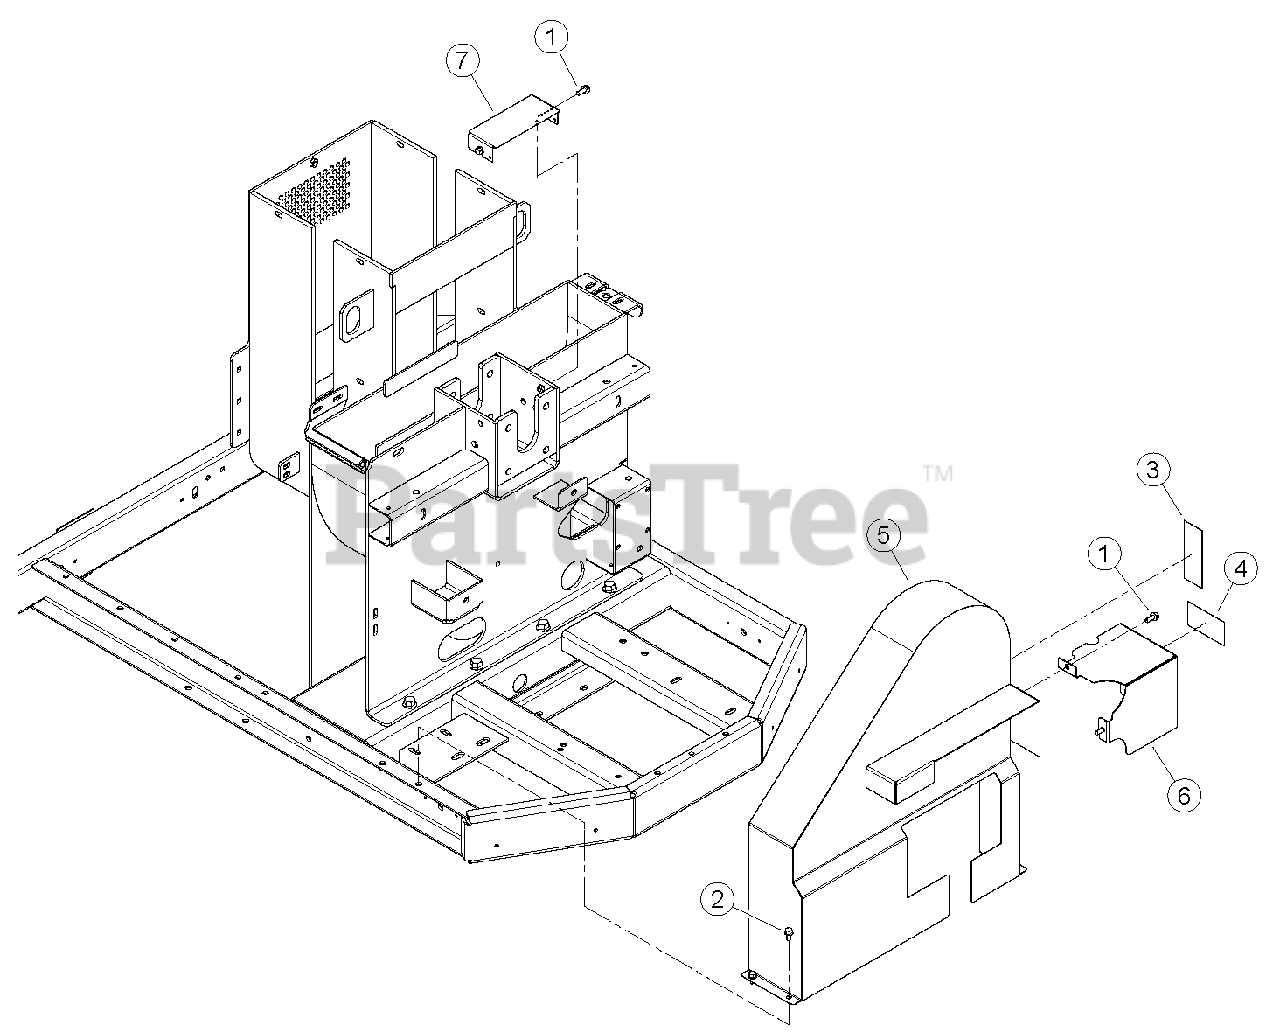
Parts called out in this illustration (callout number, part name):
1	BOLT, 5/16 X 3/4 FLANGE NC
2	BOLT, 5/16 X 5/8 FLANGE NC
3	DECAL, CHIPPER ENGAGEMENT
4	DECAL, FEED SPEED
5	WELDMENT, BELT SHIELD
6	COVER, FEED VALVE 6"
7	COVER, CHIPPER SHAFT
